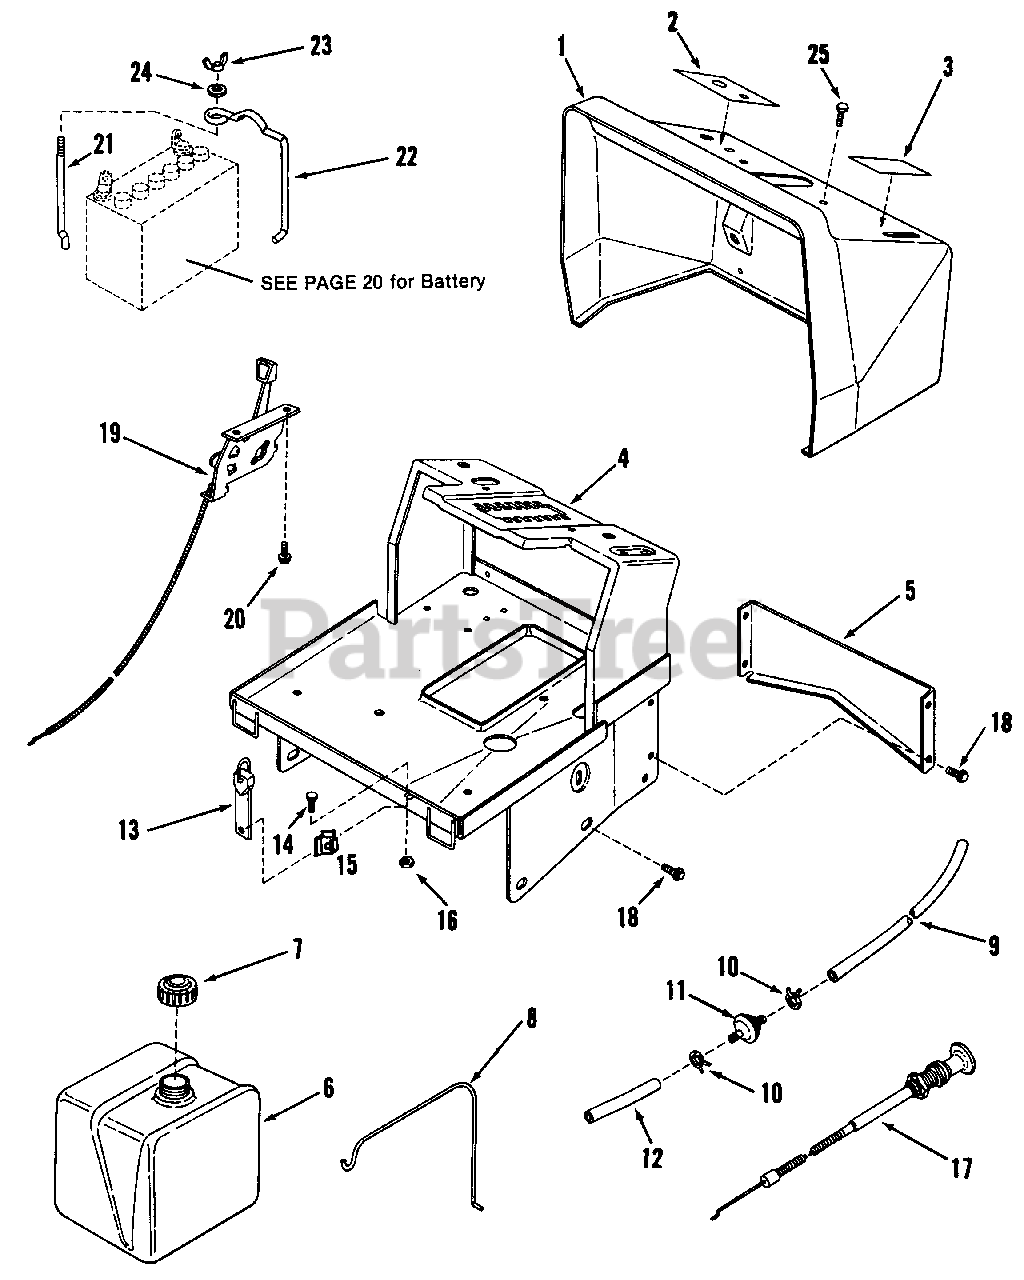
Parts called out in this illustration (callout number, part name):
1	PANEL, Dash
2	DECAL, Ignition 8 Blade
3	DECAL, Throttle
4	PEDESTAL
5	BRACKET, Lower Dash
6	TANK, Fuel
7	CAP, Fuel Tank Filler
8	HOLD-DOWN, Fuel Tank
9	LINE, Fuel (12-1/2" Long)
10	CLAMP, Fuel Line
11	FILTER, IN-LINE Fuel (75 micron)
12	LINE, Fuel (5" Long)
13	STRAP, Tank Hold Down
14	BOLT, 1/4-20 x 5/8" Flat Head Carriage, Grade 2
15	CLIP, Hood Retainer
16	NUT, 1/4-20 Hex Flange Lock, Grade 5
17	CONTROL, Choke Cable
18	SCREW, 5/16-18 x 5/8" Hex Washer Self-Tap
19	CONTROL, Throttle
20	SCREW, #10-24 x 1/2" Hex Washer Self-Tap (Torx)
21	HOLD-DOWN, Battery
22	CLAMP, Battery
23	WING-NUT, 1/4-20
24	WASHER, 1/4 Flat
25	SCREW, #10-24 x 1/2" Hex Washer Self-Tap
